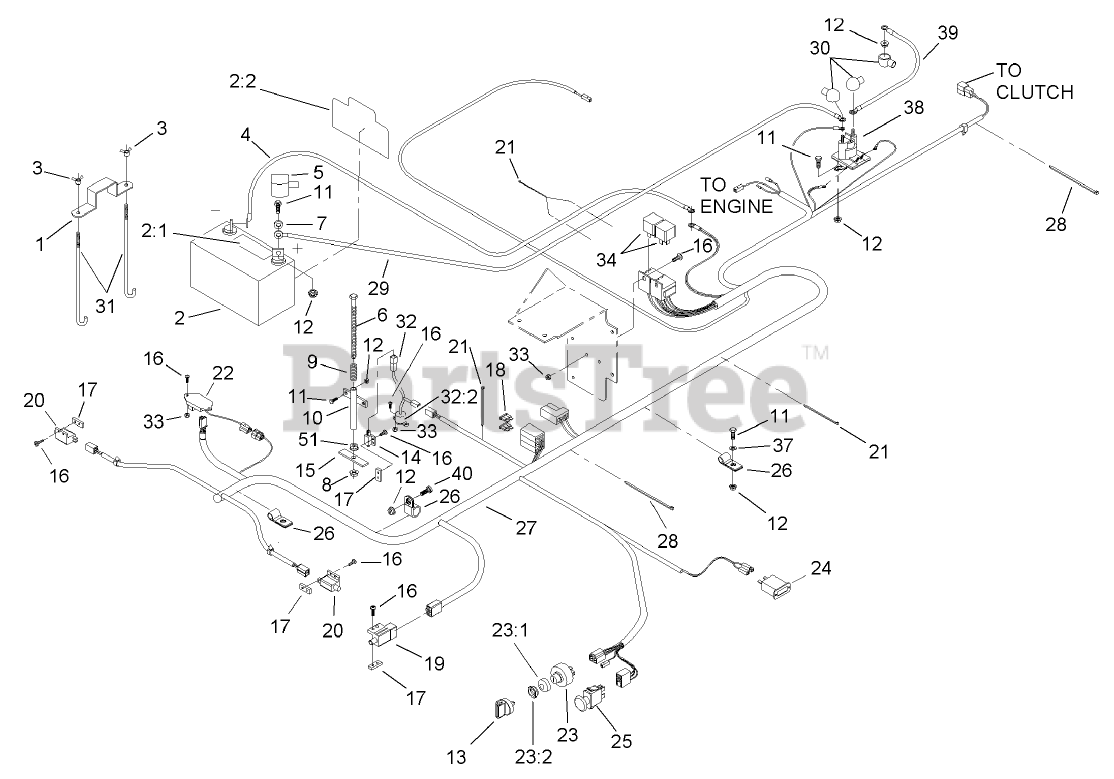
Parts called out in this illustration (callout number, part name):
1	STRAP-HOLDDOWN
2	BATTERY
2:1	Decal-Battery
2:2	Decal-Battery
3	WINGNUT
4	WIRE-GROUND
5	INSULATOR-BATTERY
6	SCREW-HH
7	WASHER-FLAT
8	NUT-LOCK, NI
9	SPRING-SWITCH, SEAT
10	MOUNT-SPRING, SEAT
11	SCREW-HH
12	NUT-HF
13	KEY-IGNITION
14	SWITCH-CLOSED, NORMALLY
15	PLATE-SWITCH, SEAT
16	SCREW-PPH
17	PLATE-TAPPED
18	FUSE-BLADE TYPE, 20 AMP
19	SWITCH
20	SWITCH-OPEN, NORMALLY
21	TIE-CABLE
22	MODULE-DELAY, SEAT
23	Key Switch ASM
23:1	WASHER-TOOTH, INTERNAL
23:2	NUT-HH
24	METER-HOUR
25	SWITCH-DELTA
26	CLIP-LOOM
27	Harness-Wire
28	TIE-PLASTIC
29	WIRE-STARTER
30	INSULATOR-SOLENOID
31	BOLT-HOLDDOWN
32	TILT SWITCH ASM
32:2	DECAL-SWITCH, MERCURY
33	NUT-LOCK, NI
37	WASHER-FLAT
38	SWITCH-SOLENOID
39	CABLE-STARTER, POSITIVE
40	SCREW-HH
51	NUT-HEX
